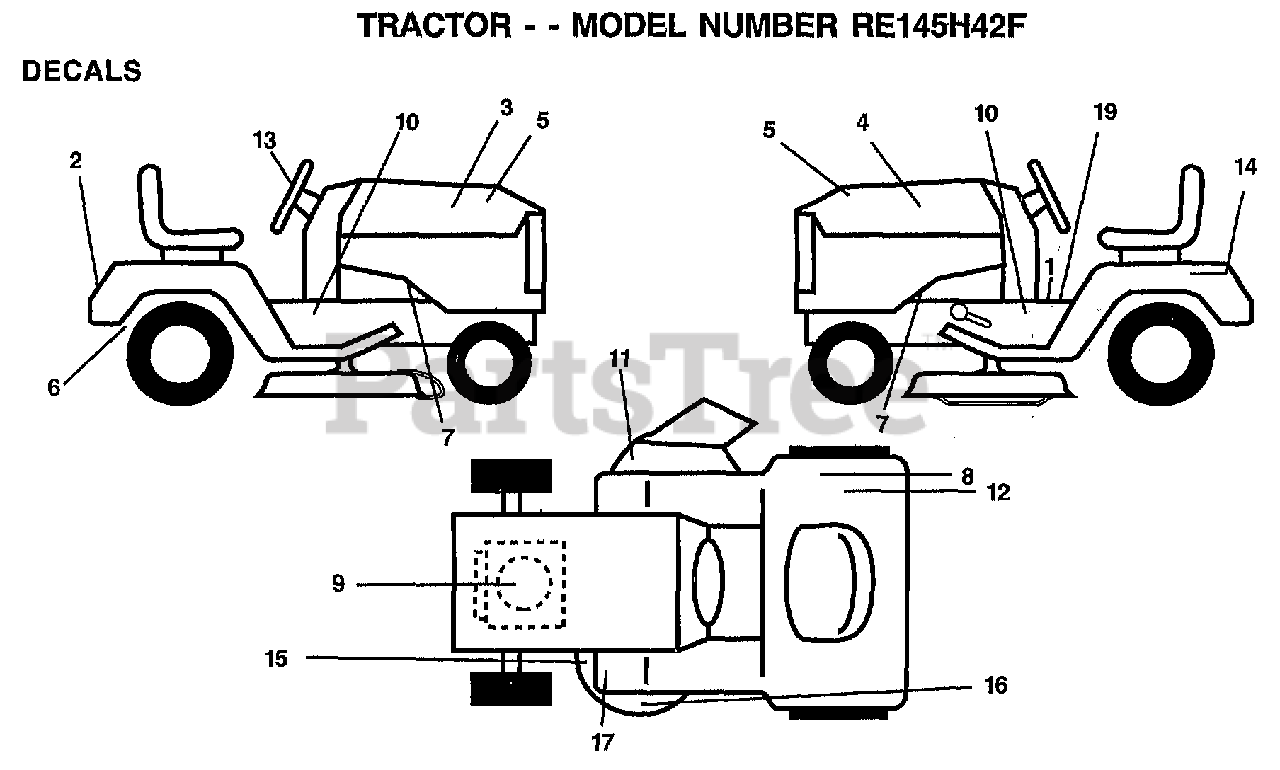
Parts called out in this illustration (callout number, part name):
1	DECAL.READ.O.MANU
2	FENDER DECAL
3	DECAL HOOD RH
4	DECAL HOOD LH
5	DECAL.INS.HD.RALL
6	DECAL.DRAWBAR.LDL
7	"DECAL CHASSIS,HOT"
8	DECAL.EURO.ST.CE.
9	DECAL, HP ENGINE
10	DECAL CHAS 42 HYD
11	DECAL.DANGER.CUTF
13	"DECAL,STR WHL"
14	DECAL.BATRY.3-3908
15	"DECAL-SCHEM,BELT"
17	DECAL-BRAKE/CLUTC
19	DECAL BRAK PARK
